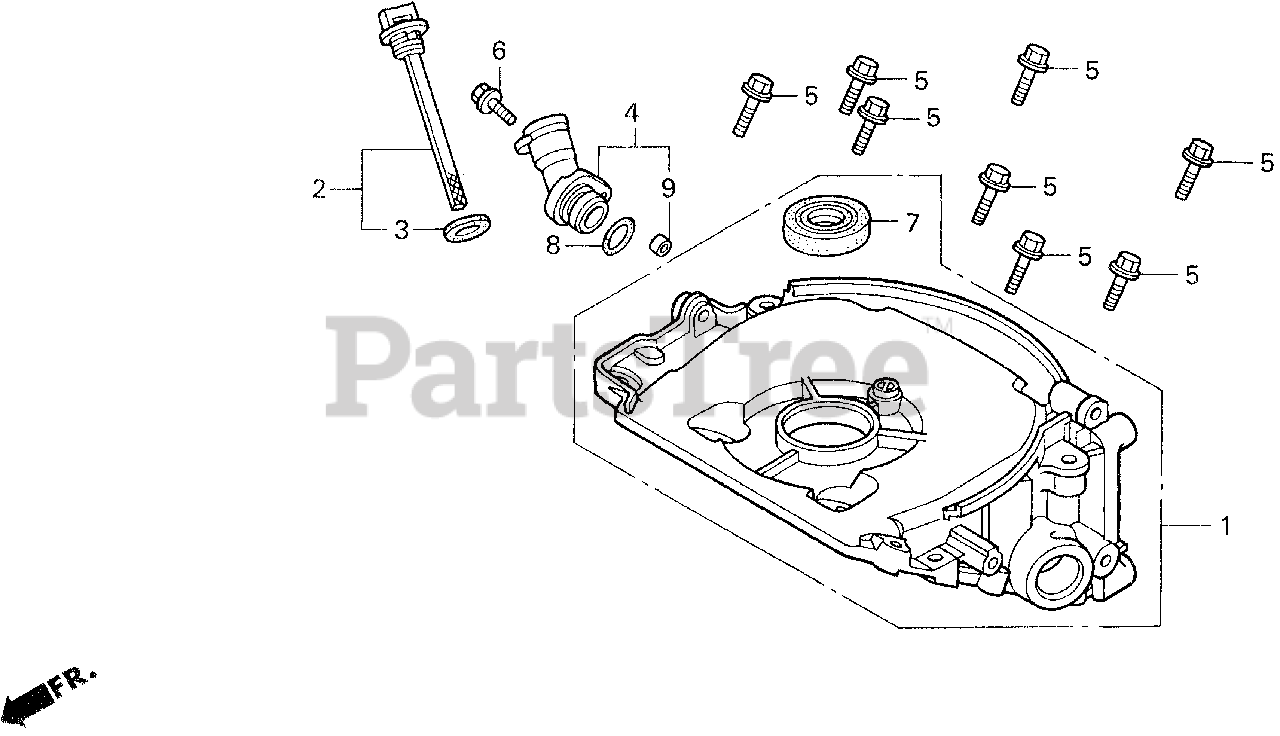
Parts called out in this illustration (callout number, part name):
1	CASE ASSY., OIL
2	CAP ASSY., OIL FILLER
3	GASKET, OIL FILLER CAP
4	EXTENSION, OIL FILLER
5	BOLT, FLANGE (5X23)
6	BOLT, FLANGE (5X14)
7	OIL SEAL (17X27X5) (KOYO)
8	O-RING (21.2X2.4) (ARAI)
9	COLLAR, TOP COVER
